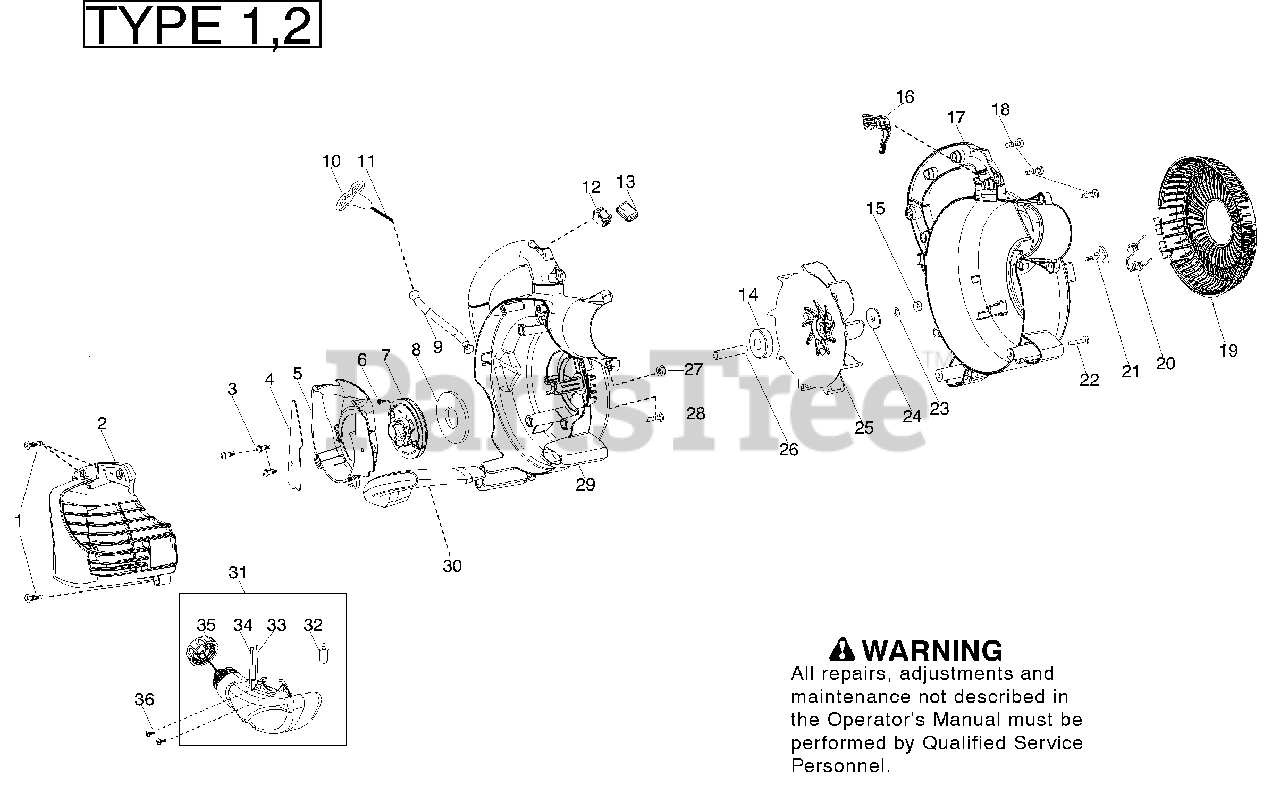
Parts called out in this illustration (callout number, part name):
2	Assy - Engine Cover
4	Shield - Baffle
7	Kit - Starter Pulley
8	Spring - Starter
9	Tube - Starter Rope
10	Handle - starter
11	Kit - Rope
12	Kit - Switch (momentary)
13	Protector - Switch
16	Trigger - Throttle
17	Assy - Scroll LH
19	Door- Vac
20	Spring - Vac Door
21	Knob - Blower
22	Screw - Handle Vac
23	Washer - Lock
24	Washer - Impeller
25	Assy-Impeller
26	Spacer - Flywheel
28	Screw
29	Assy-Scroll Assy. RH
30	Handle - Vac
31	Assy - Fuel Tank
32	Assy - Fuel Pickup
33	Kit - Fuel Line (carb/purge)
34	Kit - Fuel Line (tank/purge)
35	Assy - Fuel Cap w/retainer
36	Screw - Fuel Tank Retainer
